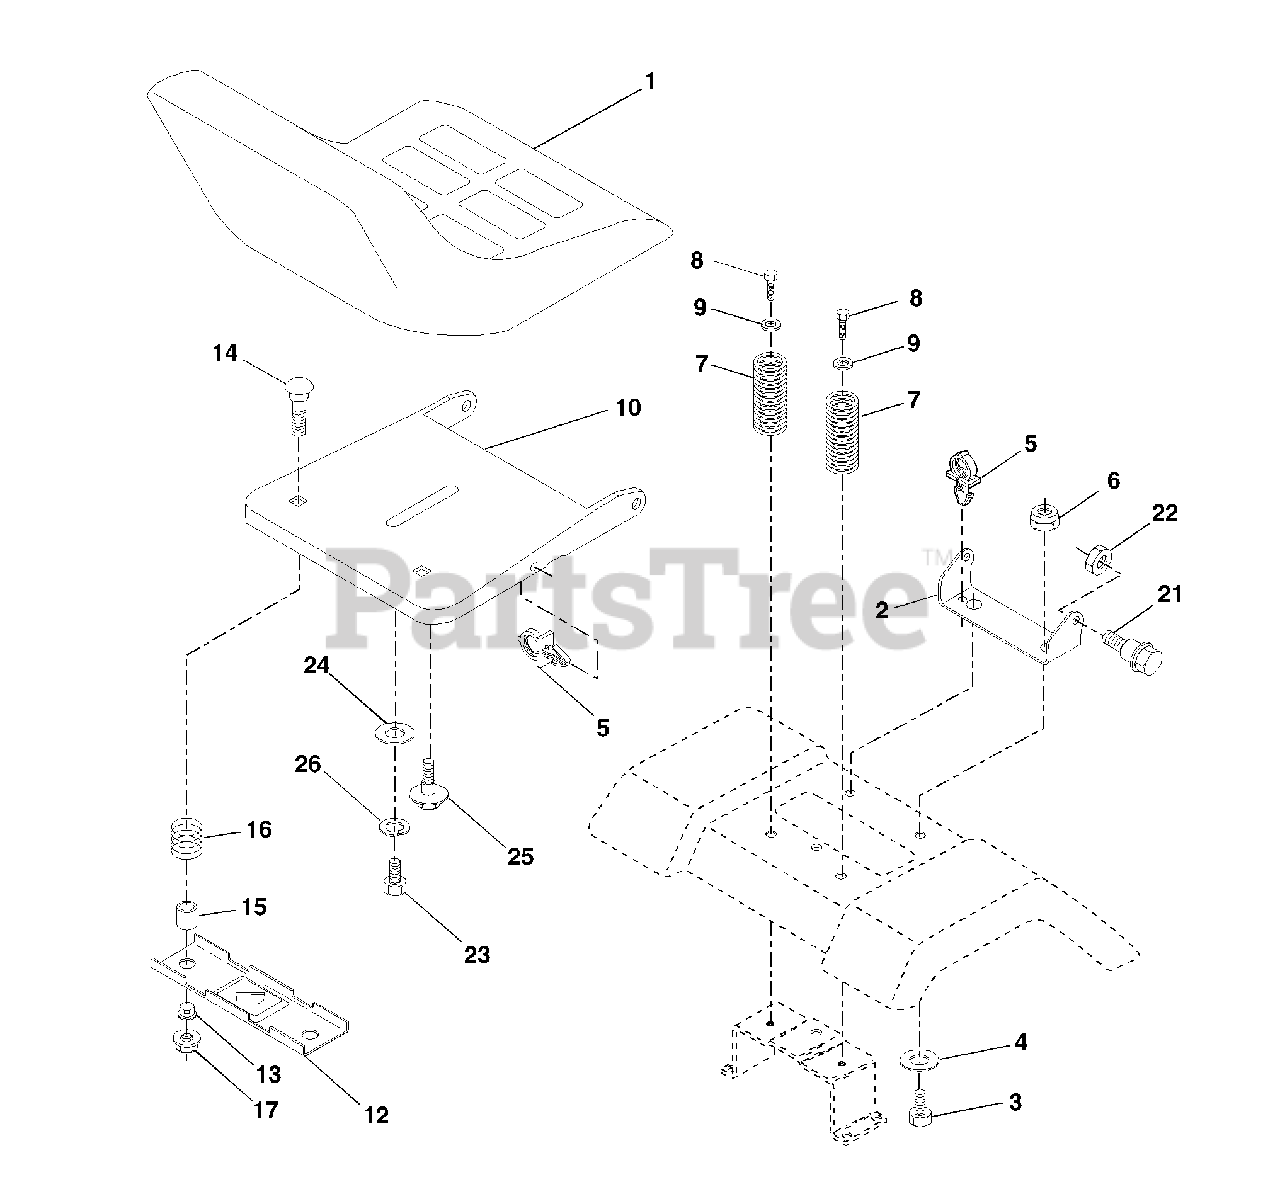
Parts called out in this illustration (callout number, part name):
2	Bracket Seat Pivot
3	Bolt Hex 3/8 - 16 X 1
4	Washer 13/32 X 1 X10Ga.
5	Clip Push-In Hinged
6	Nut Lock Hex w/Ins 3/8 - 16
7	Spring Seat Cprsn 2 250 Blk Zi
8	Screw 3/8-16 x 1.5
9	Washer 13/32 X 1 X 14 Ga
10	Pan Pnt Seat (Blk)
12	Bracket Pnt Mounting Switch
13	Bushing Snap Blk Nyl
14	Bolt Rdhd Sht Nk 1/4 - 20 X 1 -1/2
15	Spacer Split .28 X .96
16	Spring Cprsn
17	Nut Lock 1/4 Lge Flg
21	Bolt Shoulder 5/16-18 Unc-2A
22	Nut Lock Hex w/Ins 5/16 - 18
23	Bolt Hex
24	Washer 17/32 X 1-3/16 X 12 Ga
25	Bolt Shoulder 5/16-18 X .62
26	Washer Lock Hvy Hlcl Spr 1/2
